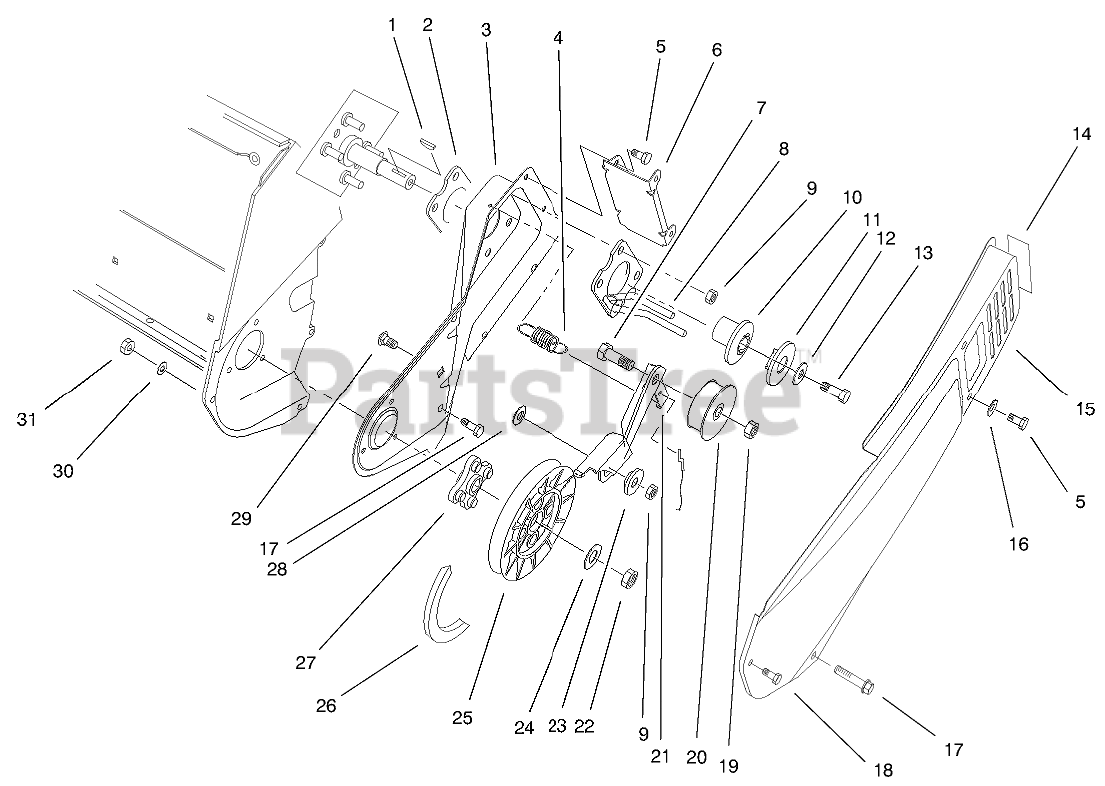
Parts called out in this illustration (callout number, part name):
1	KEY-WOODRUFF
2	PLATE-ENGINE
3	SIDEPLATE-LH
4	SPRING-BRAKE
5	SCREW-HWH
6	BRACKET-COVER, BELT
7	SCREW-HH
8	GUIDE-BELT
9	NUT-LOCK, NI
10	Hub-HALF SHEAVE
11	CAP-HALF SHEAVE
12	WASHER-FLAT
13	SCREW-HH
14	DECAL-HOT
15	COVER-BELT
16	WASHER-FLAT
17	SCREW-PLASTIC
19	NUT-LOCK, NI
20	PULLEY-IDLER
21	ARM-BRAKE
22	NUT-LOCK, NI
23	BUSHING-IDLER
24	WASHER-FLAT
25	PULLEY-DRIVEN
26	V BELT
28	WASHER
29	SCREW-CARR
30	WASHER-FLAT
31	NUT-LOCK, NI
